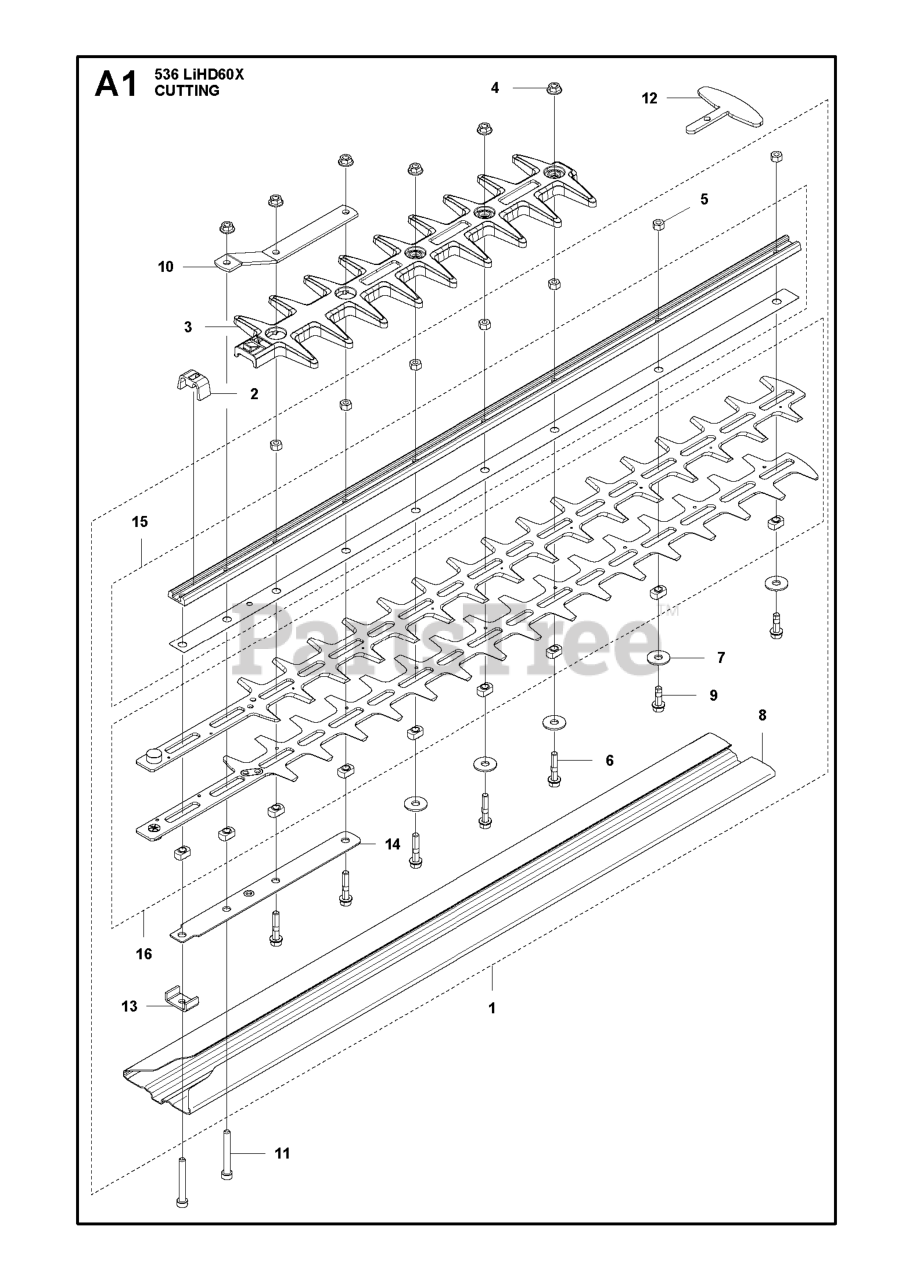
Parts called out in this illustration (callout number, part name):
1	CUTTING DECK LIHD HD60 INCR. S
3	PROTECTION ASSY BLADE
4	HEXAGON NUT FLANGE M5 8 ZN/FE
6	SCREW IHSCFM M5X25 10.9 ZN/FE
7	WASHER 6,4X18X1,5
8	TRANSPORT GUARD CUTTING DECK H
9	SCREW M5X16 T25
10	SUPPORT CUTTING DECK
11	SCREW IHSCT EN ISO 4762 / DIN
12	PROTECTION BLADE TIP
13	BRACKET
15	CUTTING DECK KIT
16	CUTTING DECK KIT
